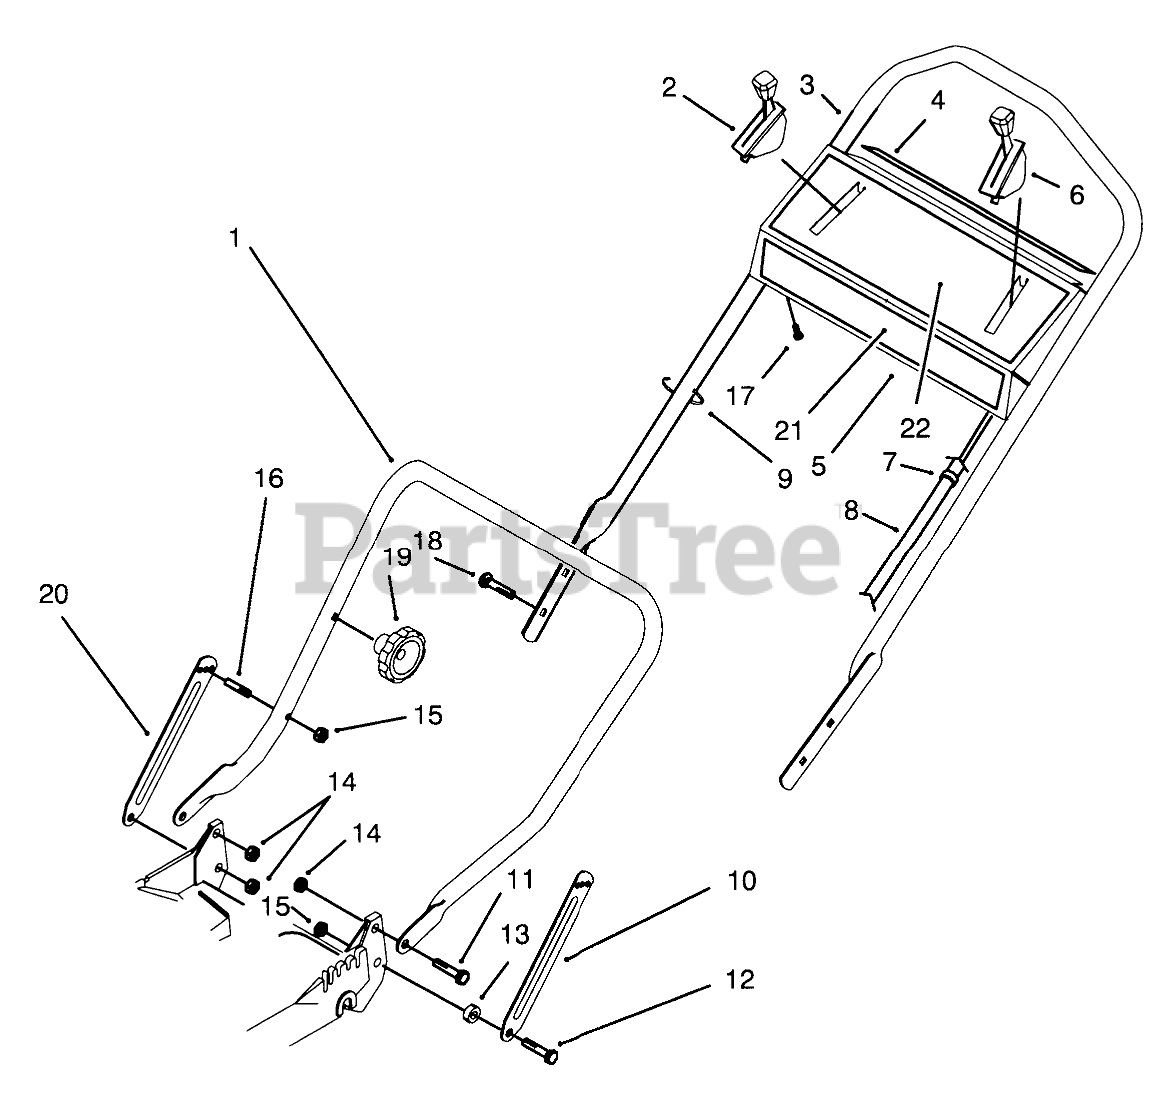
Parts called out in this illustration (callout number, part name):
1	LOWER HANDLE ASM
2	CONTROL-SPEED, GROUND
3	UPPER HANDLE, PVC DIP
4	DECAL - PANEL, REAR
5	Panel-Control (Incl. Ref. #4 & 22)
6	THROTTLE CONTROL
7	FITTING-RING
8	CONTROL CABLE COVER
9	TIE-CABLE
10	LH HANDLE LATCH
11	SCREW-SHOULDER
12	SCREW-SHOULDER
13	SPACER
14	NUT-LOCK, NI
15	NUT-LOCK, NI
16	HANDLE PIN
17	10-16X1/2 SHWH SCREW
18	5/16-18 X 2 HNDLE SCREW
20	RH HANDLE LATCH
21	DECAL - PANEL (TORO)
22	DECAL - INSTRUCTION
